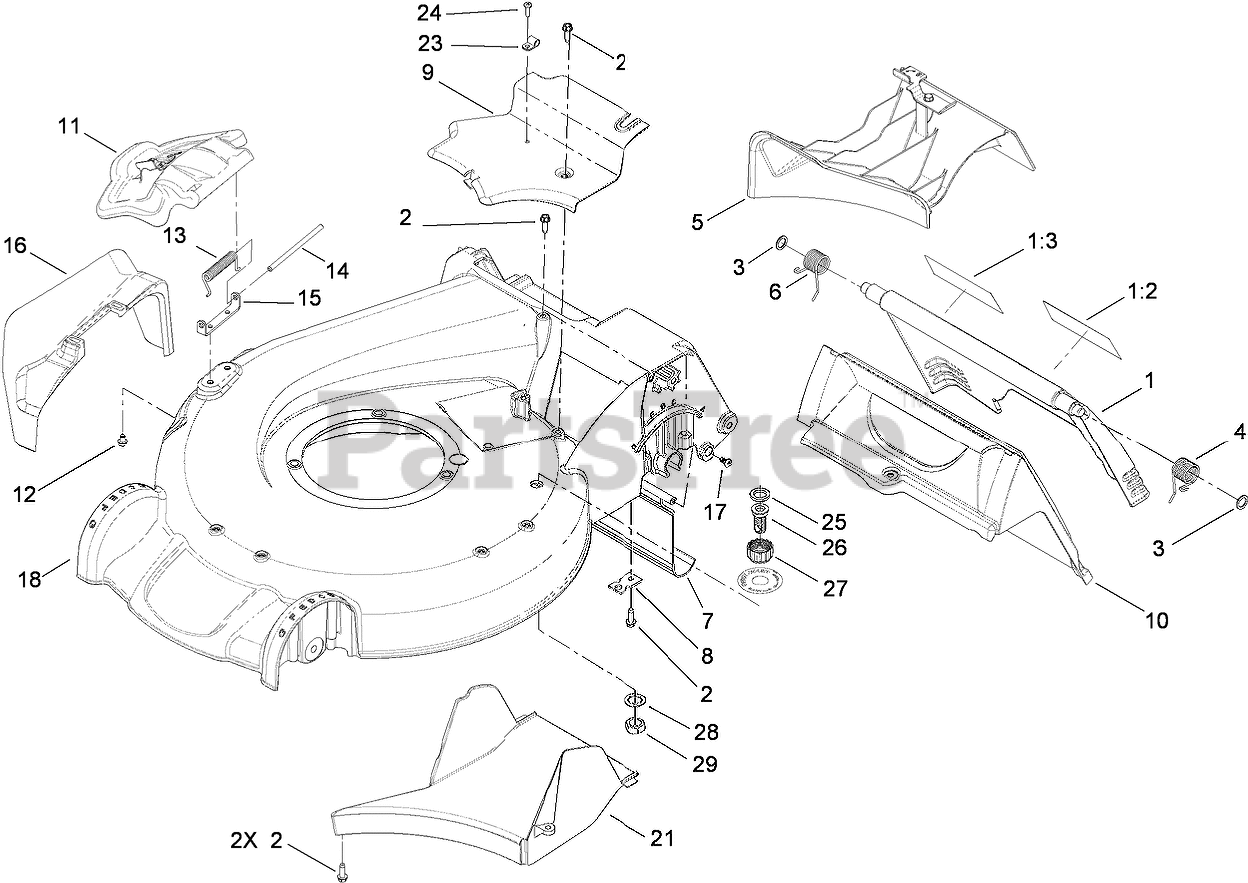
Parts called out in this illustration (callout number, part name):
1	REAR DOOR ASM
1:2	DECAL-WARNING
1:3	DECAL-WARNING
2	SCREW-HWHTF
3	WASHER-NYLON
4	SPRING-TORSION
5	MULCH PLUG ASM
6	SPRING-TORSION
7	SHIELD-TRAILING
8	BRACKET-CABLE, TRACTION
9	COVER-BELT
11	DISCHARGE DOOR ASM
12	SCREW-HWH
13	SPRING-TORSION
14	ROD-COVER
15	BRACKET-COVER
16	CHUTE-DISCHARGE, SIDE
17	SCREW-PTH
18	HOUSING ASM
21	TUNNEL-DISCHARGE
23	CLAMP
25	WASHER-SEAL, WASHOUT PORT
26	PORT-WASHOUT
27	COUPLING-HOSE, WASHOUT PORT
28	WASHER-TOOTH, INTERNAL
29	NUT-JAM
